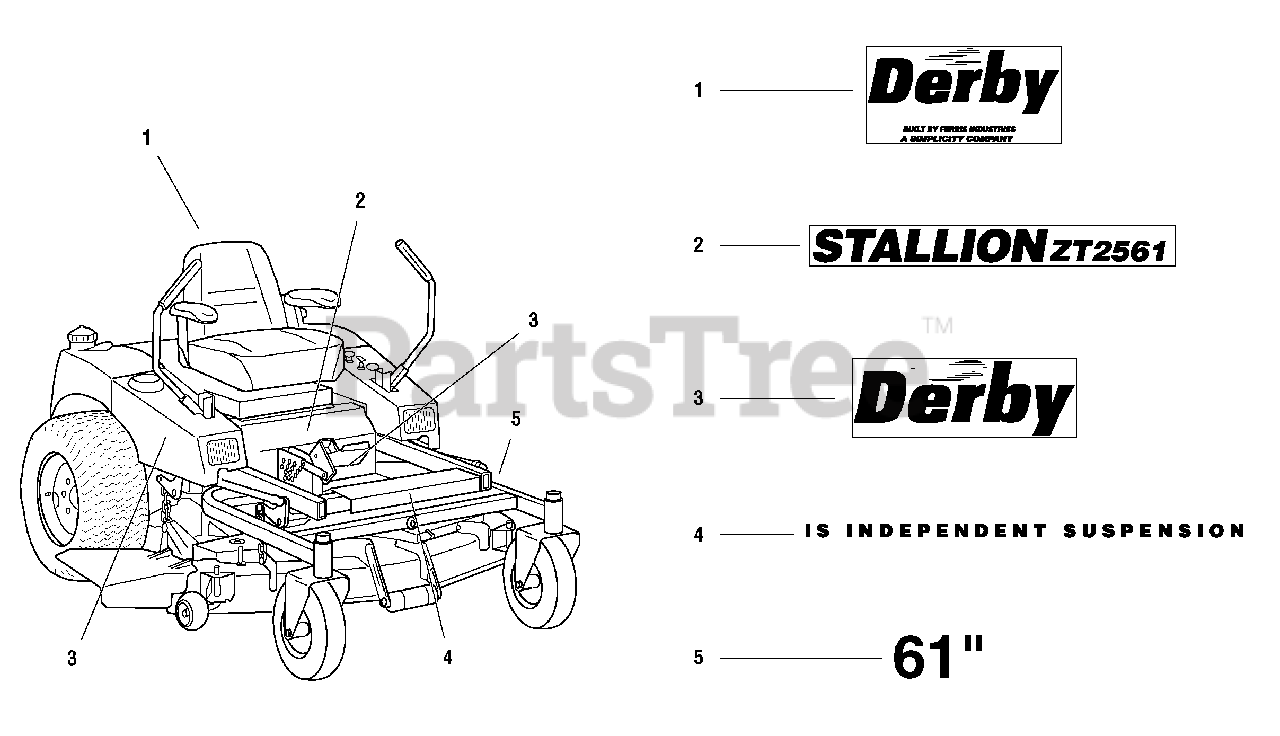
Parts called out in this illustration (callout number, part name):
1	DECAL, Derby Built By Ferris (located on back of seat)
2	DECAL, Stallion ZT2561
3	DECAL, Derby
4	DECAL, IS Independent Suspension
5	DECAL, 61" (LH guard end)
